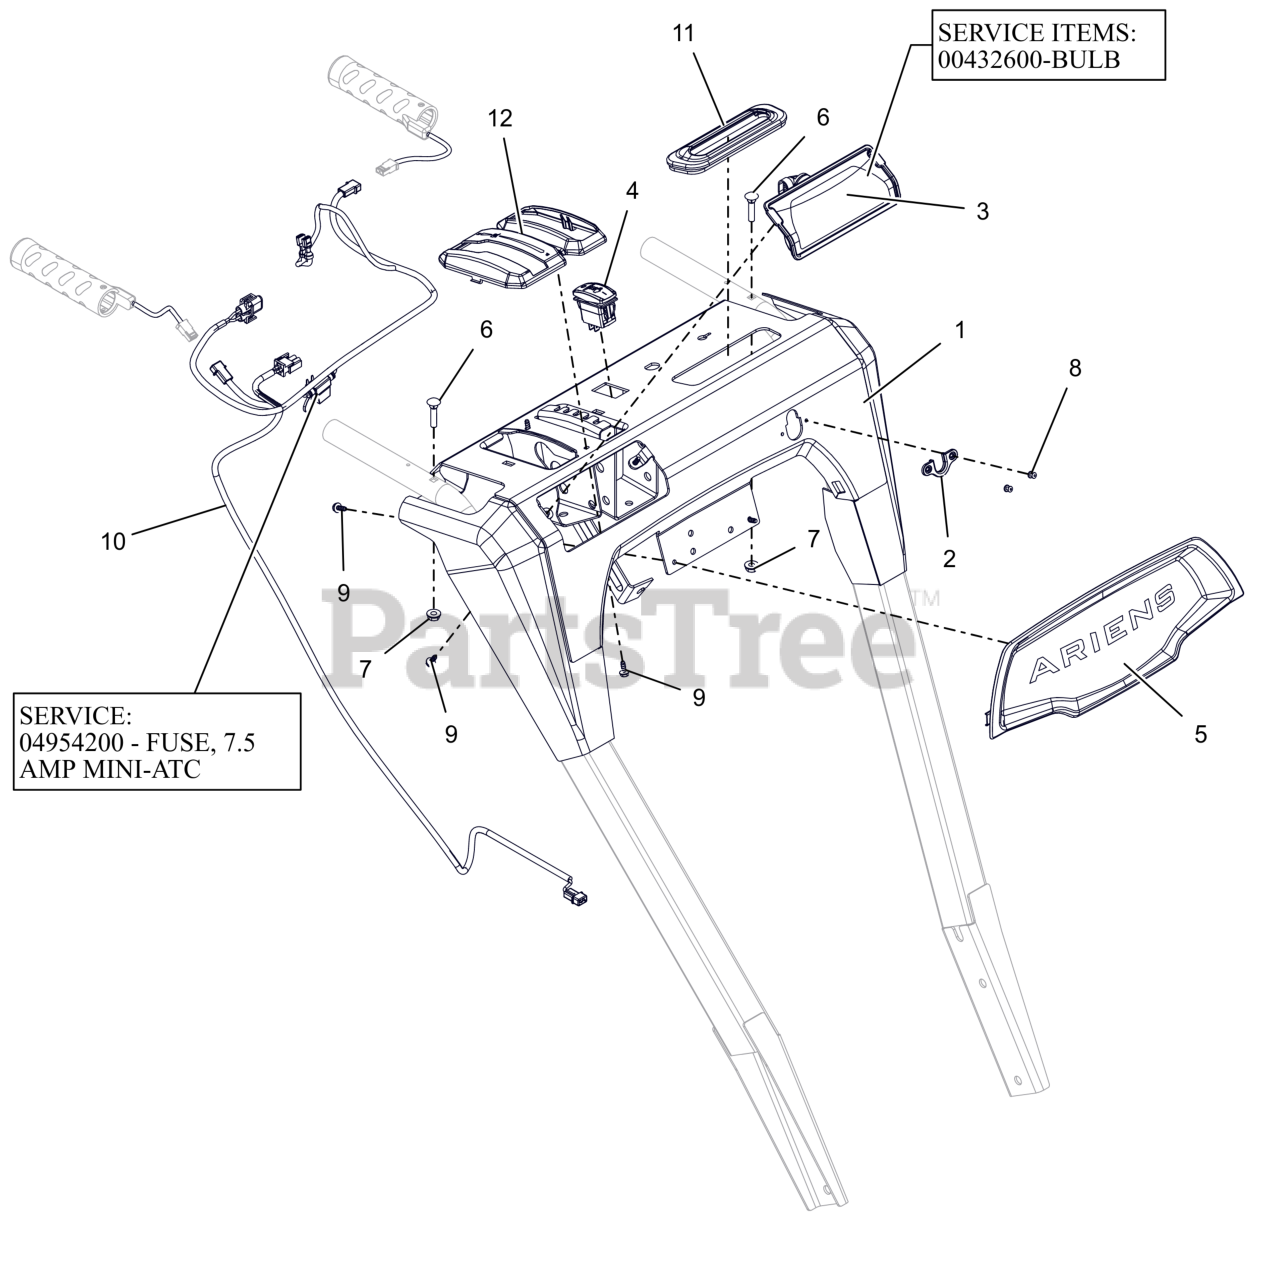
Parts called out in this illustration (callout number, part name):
1	PANEL, DASH-HYDRO EFI W/DECAL
2	GROMMET, CABLE, QUICK TURN 2
3	HEADLIGHT ASY, HALO 20W 2SHOT
3	BULB, LIGHT-HALOGEN 20W
4	SWITCH,ROCKER SPST-ON/OFF
5	BEZEL, DASH - ARIENS LG DASH
6	BLT-RDHDXLSQNK.25-20X1.25 G5ZC
7	NUT-LK-CTR-FLG .25-20 ZC120
8	RVT-POP #43 .125X.313 STL ZINC
9	SCR, PLASTIC #10X.50
10	HARNESS,LIGHT&WARMER - EFI
10	FUSE, 7.5 AMP MINI-ATC
11	GROMMET, BOOT, QUICK TURN
12	BEZEL, SHIFT - HYDRO SNOW
